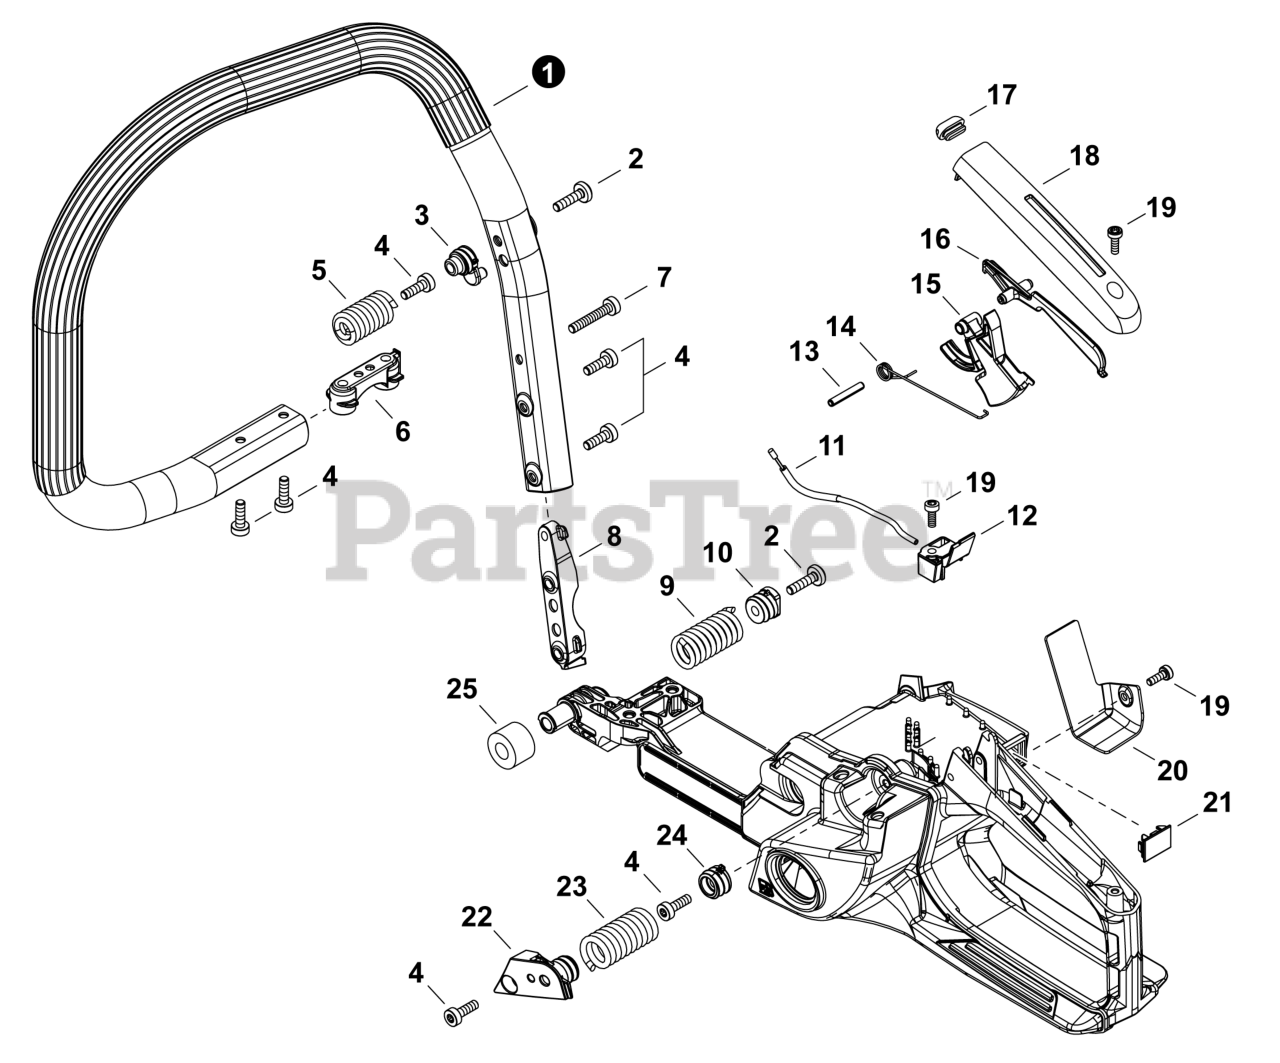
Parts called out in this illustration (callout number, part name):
1	HANDLE, FRONT
2	BOLT, TORX 6x20
3	HOLDER, SPRING
4	BOLT, TORX 5x16
5	SPRING, COMPRESSION
6	BRACKET, HANDLE
7	BOLT, TORX 5x30
8	BRACKET, HANDLE
9	SPRING, COMPRESSION
10	HOLDER, SPRING
11	CABLE, THROTTLE
12	GUIDE, CABLE
13	PIN, SPRING 4x25 SUS
14	SPRING, TORSION
15	CONTROL, THROTTLE
16	LOCKOUT, THROTTLE
17	CUSHION
18	COVER, HANDLE
19	BOLT, TORX 4x12
20	PROTECTOR, CUSHION
21	GROMMET, PLUG
22	HOLDER, SPRING
23	SPRING, COMPRESSION
24	HOLDER, SPRING
25	CUSHION 10
